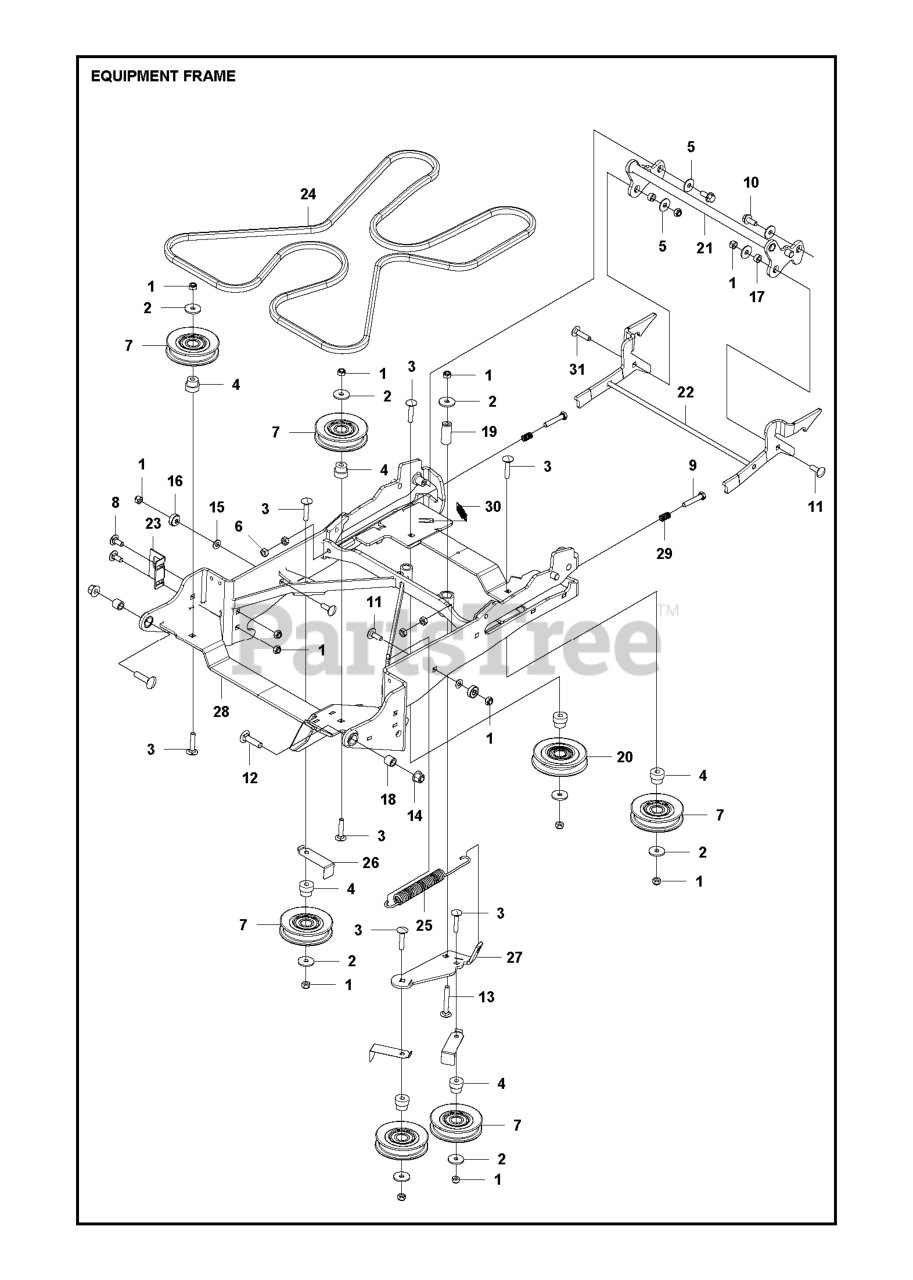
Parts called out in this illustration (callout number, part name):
1	LOCKNUT M8
3	Screw Mvbf 8 X 40
6	NUT
15	WASHER BRB 8.4X17
16	BALL BEARING
